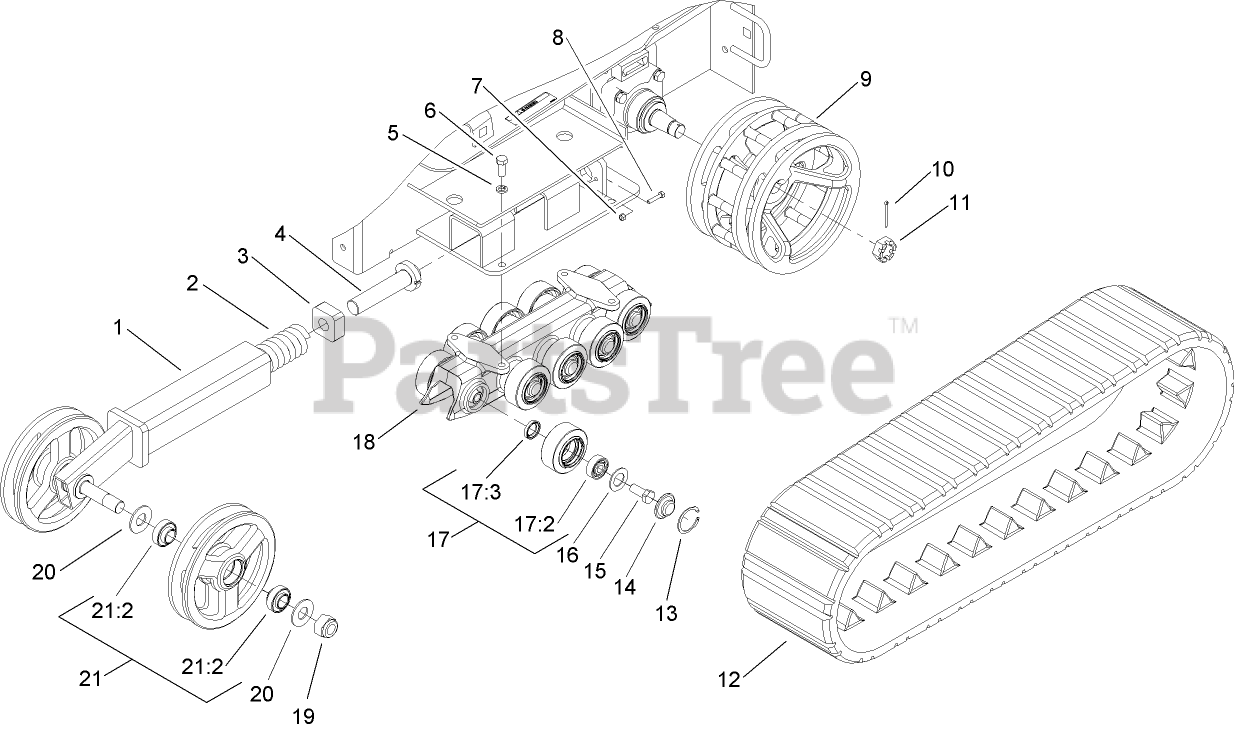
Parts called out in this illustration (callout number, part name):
1	TENSIONER ARM ASM
2	SPRING-COMPRESSION
3	BLOCK-TENSIONER
4	BOLT-TENSIONER
5	WASHER-LOCK
6	SCREW-HH
7	NUT-LOCK, NI
8	SCREW-HH
9	WHEEL-DRIVE, TX 425
10	PIN-COTTER
11	NUT-HEX SLOTTED
12	TRACK
13	RING-SNAP, INTERNAL
14	CAP-WHEEL, BEARING
15	SCREW-HH
16	Gasket-Bogie
17	Road Wheel ASM
17:2	BEARING
17:3	SEAL-OIL
18	GUIDE-TRACK
19	NUT-HEX, NI
20	Washer-Flat
21	Tensioner Wheel ASM
21:2	Bearing-Ball
